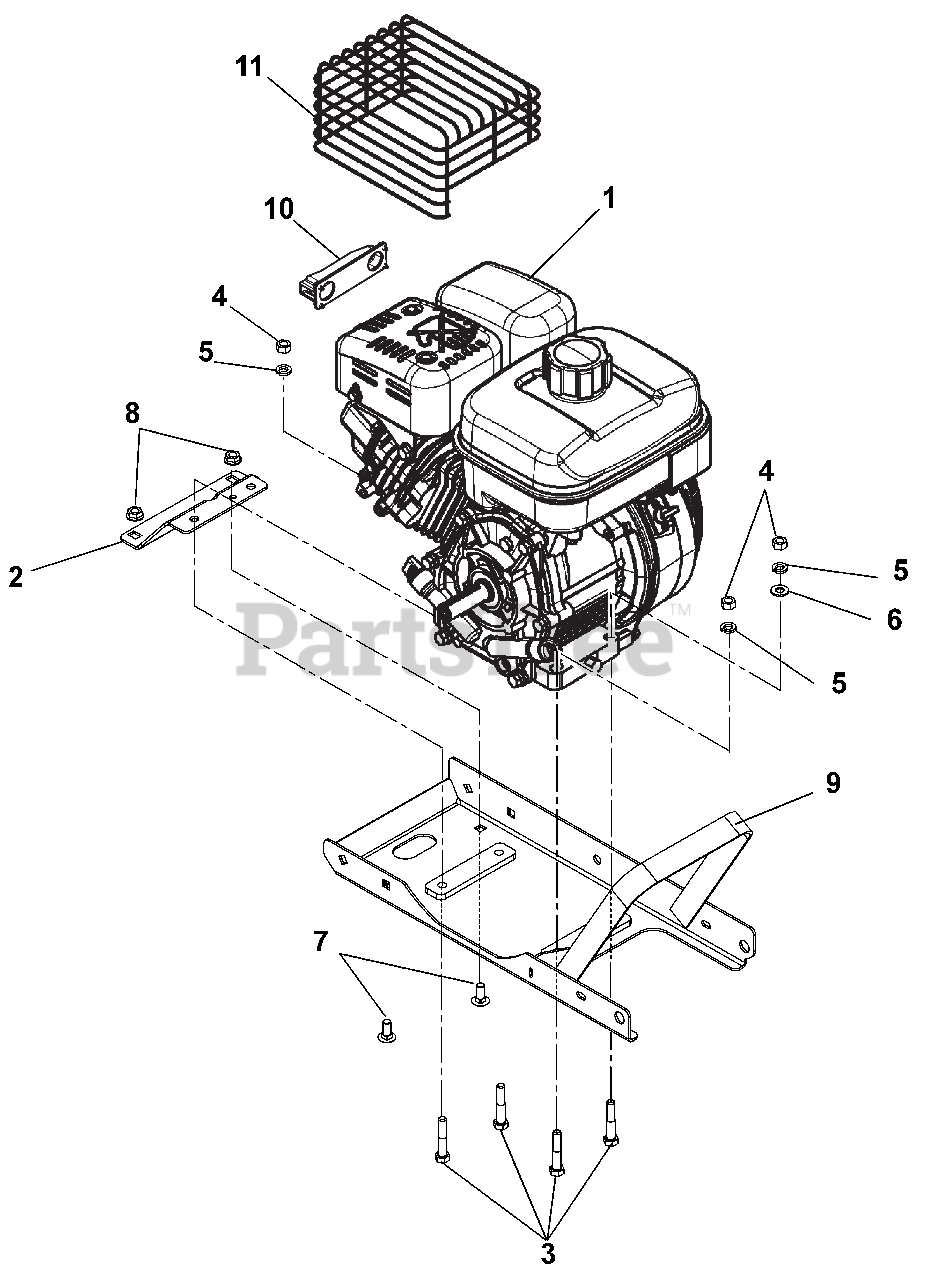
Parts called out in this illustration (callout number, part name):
1	ENGINE,SUBARU 6HP SP170 (CARB)
1	ENGINE, LCT-136 (CARB)
2	BRACKET, REINFORCEMENT
3	@BLT-HEX .31-18X1.75 GR5 YWZC
4	@NUT-HEX .31-18 YWZC
5	WSHR-LK .312X.097 HVY YWZC
6	@WSHR-FL-STL.344X.688X.065YWZC
7	@BLT-RDHDSQNK .31-18X.75 G5YZ
8	@NUT-LK-TOP-FLG .31-18 YWZC
9	FRAME,EDGER
10	KIT, LCT EXHAUST DEFLECTOR
11	GUARD,MUFFLER,SUB 20A-37303-11
